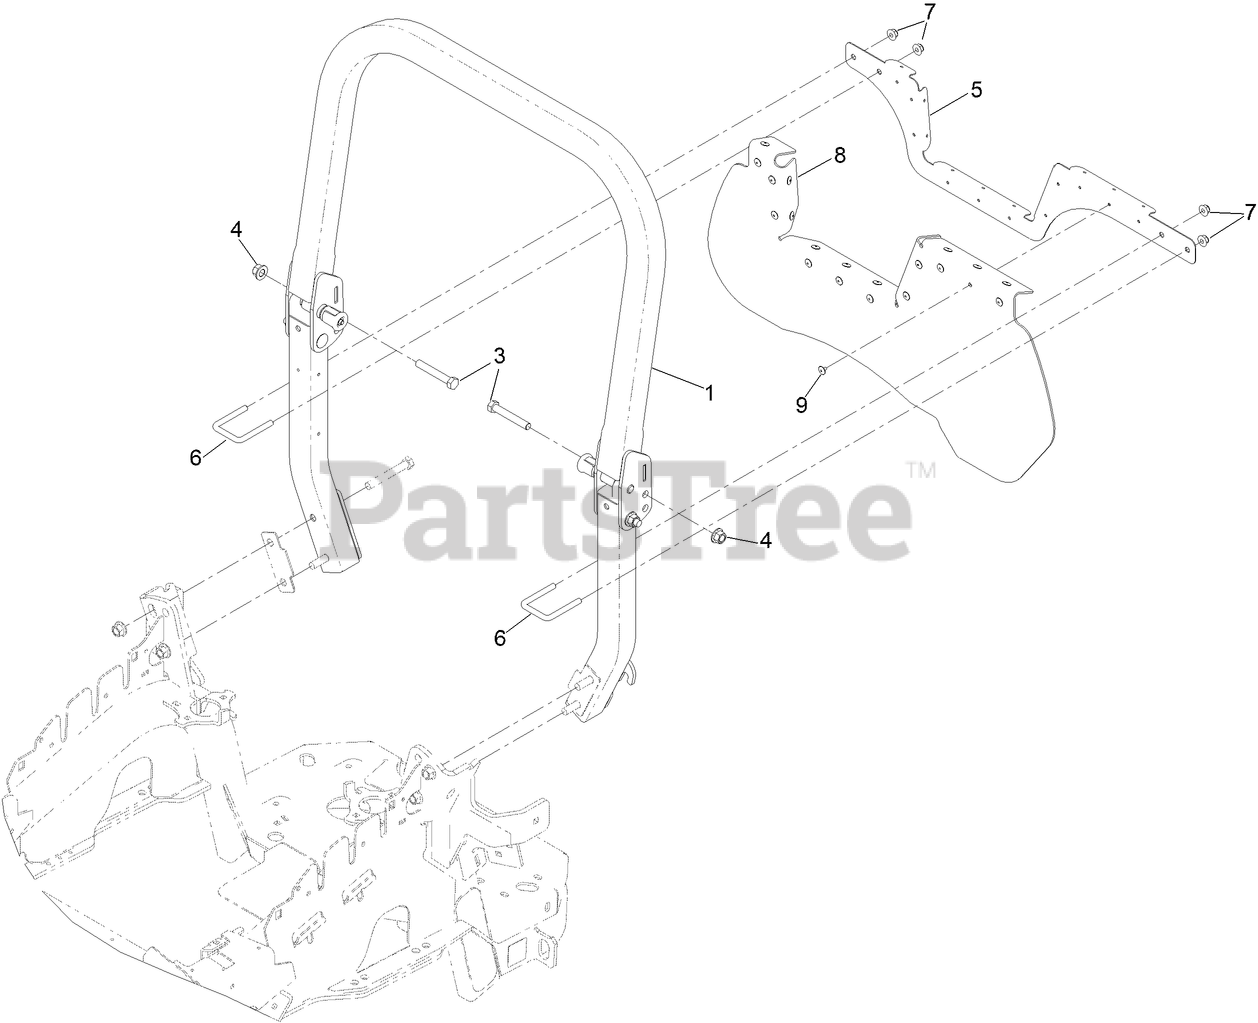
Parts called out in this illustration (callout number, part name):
1	ROPS ASM
3	SCREW-HH
4	NUT-LOCK
5	BRACKET, AIR DAM
6	U-BOLT
7	NUT-HF, NI
8	AIR DAM, HOOD
9	RIVET-POP
